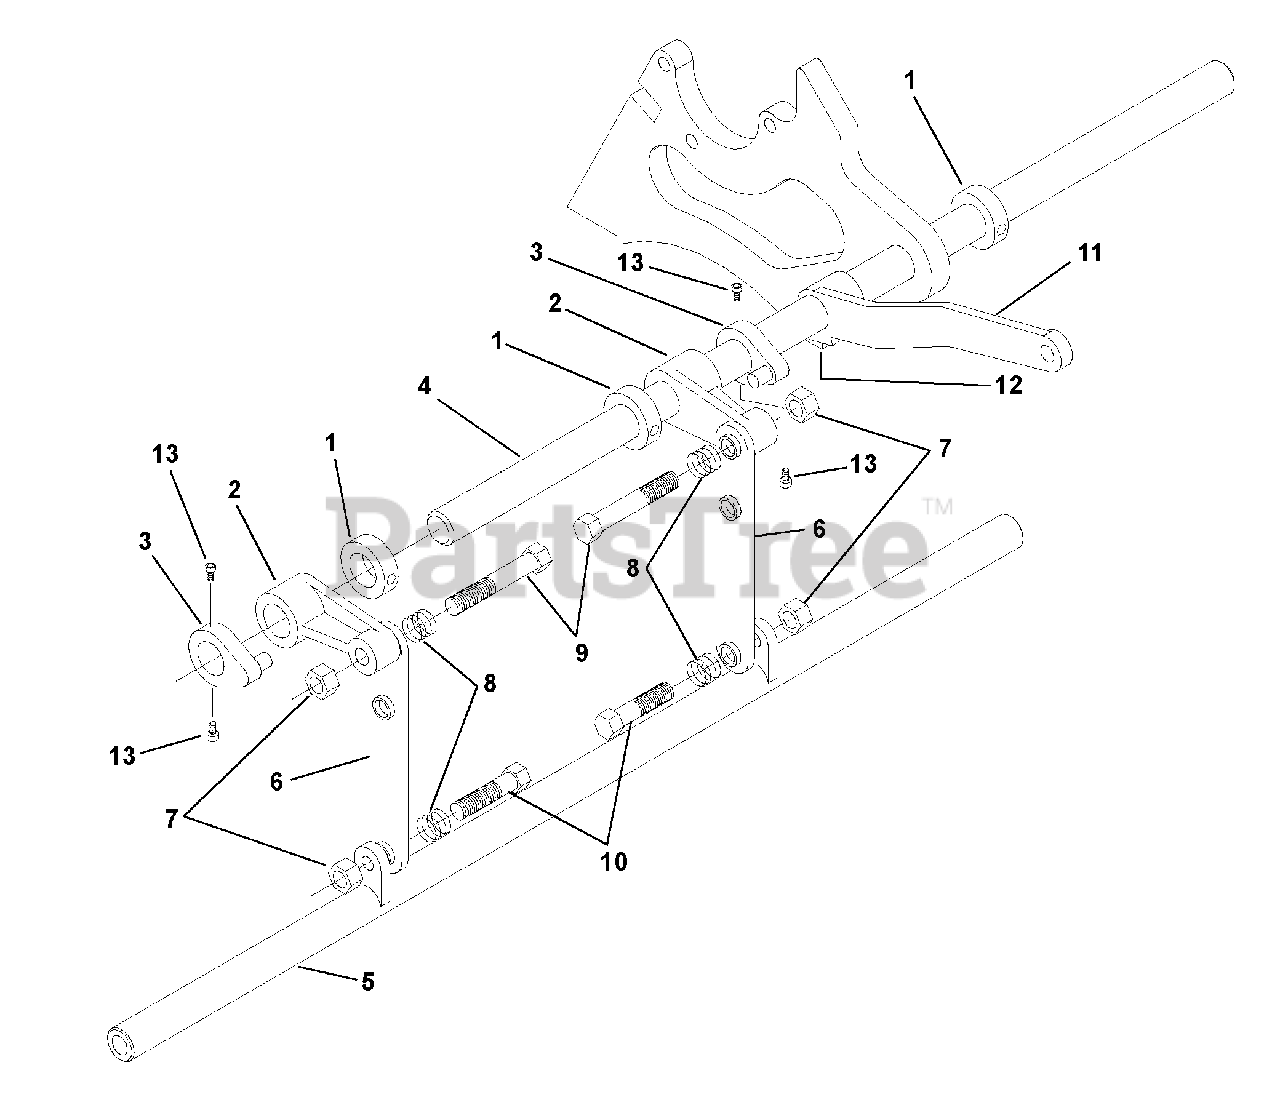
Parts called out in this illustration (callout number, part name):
2	Arm,Reel Lift
3	Collar,Lift
4	Shaft,Lift 25-inch
5	Bar, Spacer 25-Inch
7	Nut,Hex .38-16
9	Cap Screw Hex Head .38-16 x 1.75
10	Cap Screw Hex Head .38-16 x 1.50
11	Lever, Reel Lift
12	Set Screw, Socker .312-24 x .25 Stainless Steel
13	Set Screw, Hex Socket Head .25 x .38 Grade 8
